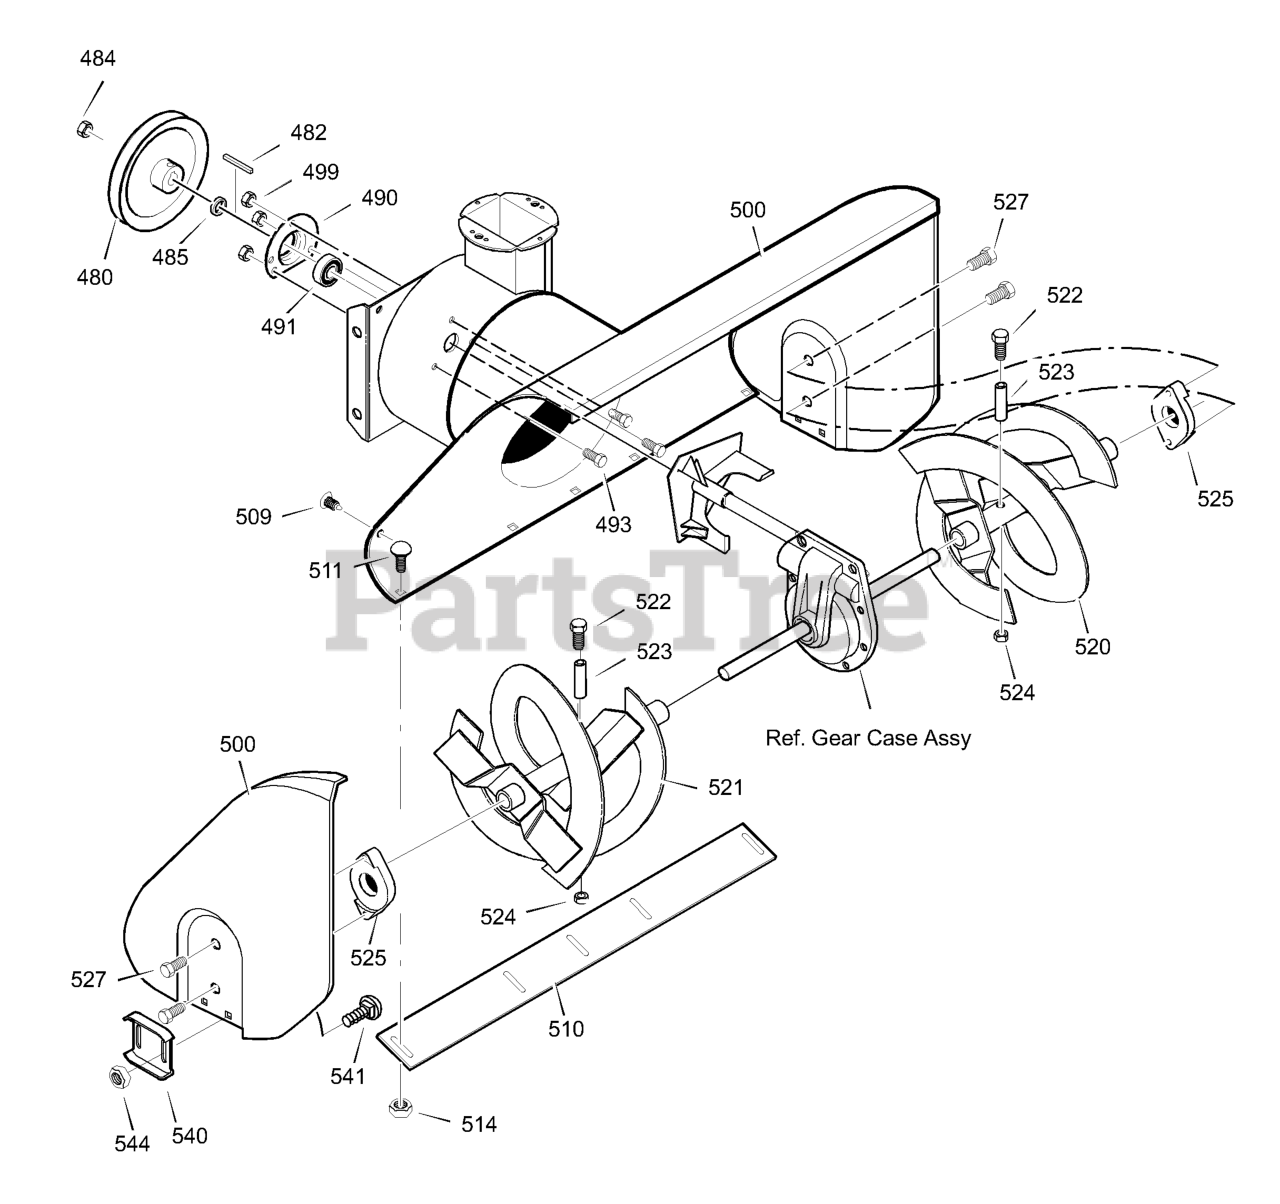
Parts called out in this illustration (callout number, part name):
480	PULLEY, 4L 8.40 OD
482	KEY, SQUARE
484	NUT, 1/2-20
485	SPACER, FRICTION PULLEY
490	RETAINER, BALL BRNG
491	BEARING, BALL
493	BOLT, HEX - 0.31-18X0.50
499	NUT, 5/16-18 HEXWDFLLK
500	HOUSING, ASSY
509	PLUG, CHRISTMAS TREE
510	BLADE, SCRAPER
511	BOLT, CARRIAGE
520	AUGER, ASSY, LH
521	AUGER, ASSY, RH
522	BOLT, 1/4-20 x 1.75
523	SPACER, SLEEVE
524	NUT, 1/4-20
525	BEARING, AUGER SHAFT 1" ID
527	SCREW, 5/16-18 x 0.75
536	BOLT, 5/16-18 x .75
540	SKID, HEIGHT ADJUST
541	BOLT, 5/16-18 X .75
544	NUT, 5/16-18 REGHEX
